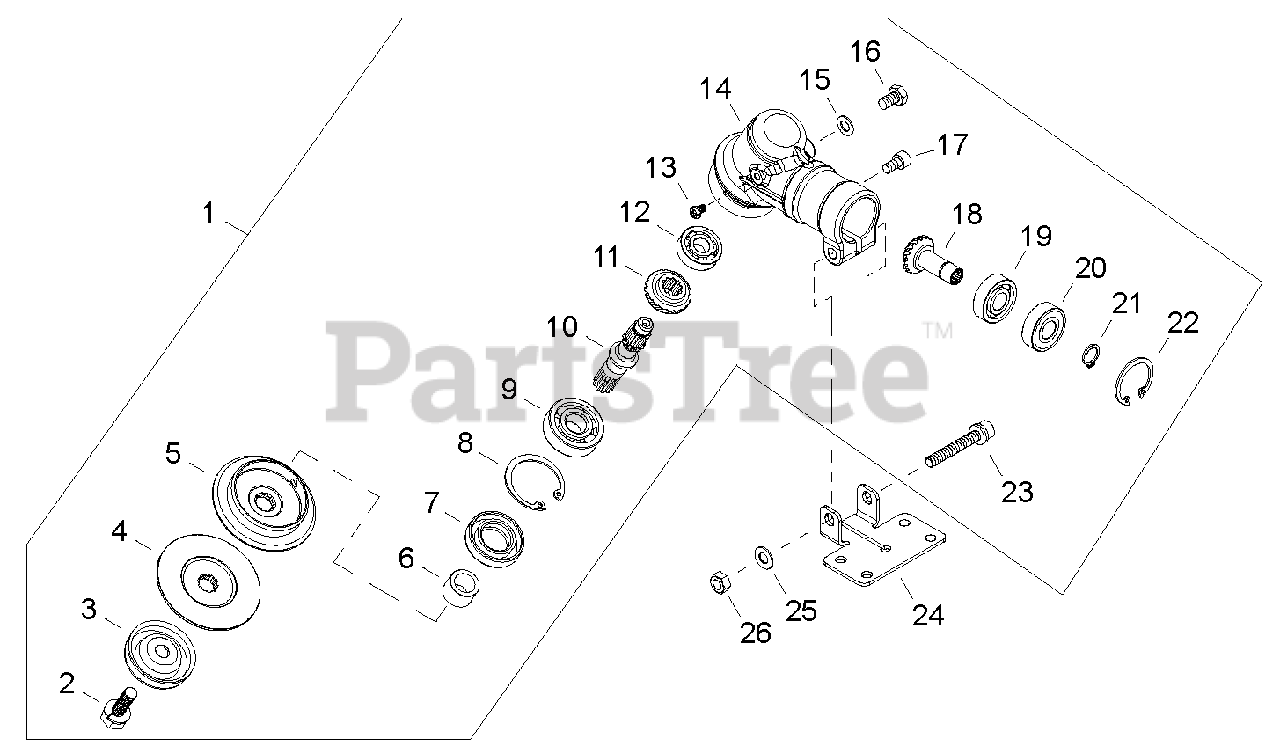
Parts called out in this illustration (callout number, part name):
1	GEAR CASE ASSY
2	SCREW - 8X22
3	GUARD
4	ADAPTOR, BLADE - LOWER
5	ADAPTOR, BLADE - UPPER
6	COLLAR
7	SEAL, OIL
8	RING, RETAINING - 32
9	BEARING, BALL - 6201
10	GEAR - SHAFT
11	GEAR - BEVEL
12	BEARING, BALL - 609
13	SCREW - 4X6
14	CASE, GEAR
15	WASHER - 6
16	BOLT - 6X10
17	SCREW - 5X10
18	GEAR - BEVEL
19	BEARING, BALL - 6000
20	BEARING, BALL - 6000Z
21	RING, RETAINING - 10
22	RING, RETAINING - 26
23	SCREW - 6X40
24	MOUNTING PLATE, SHIELD
25	WASHER - 6
26	NUT - 6
